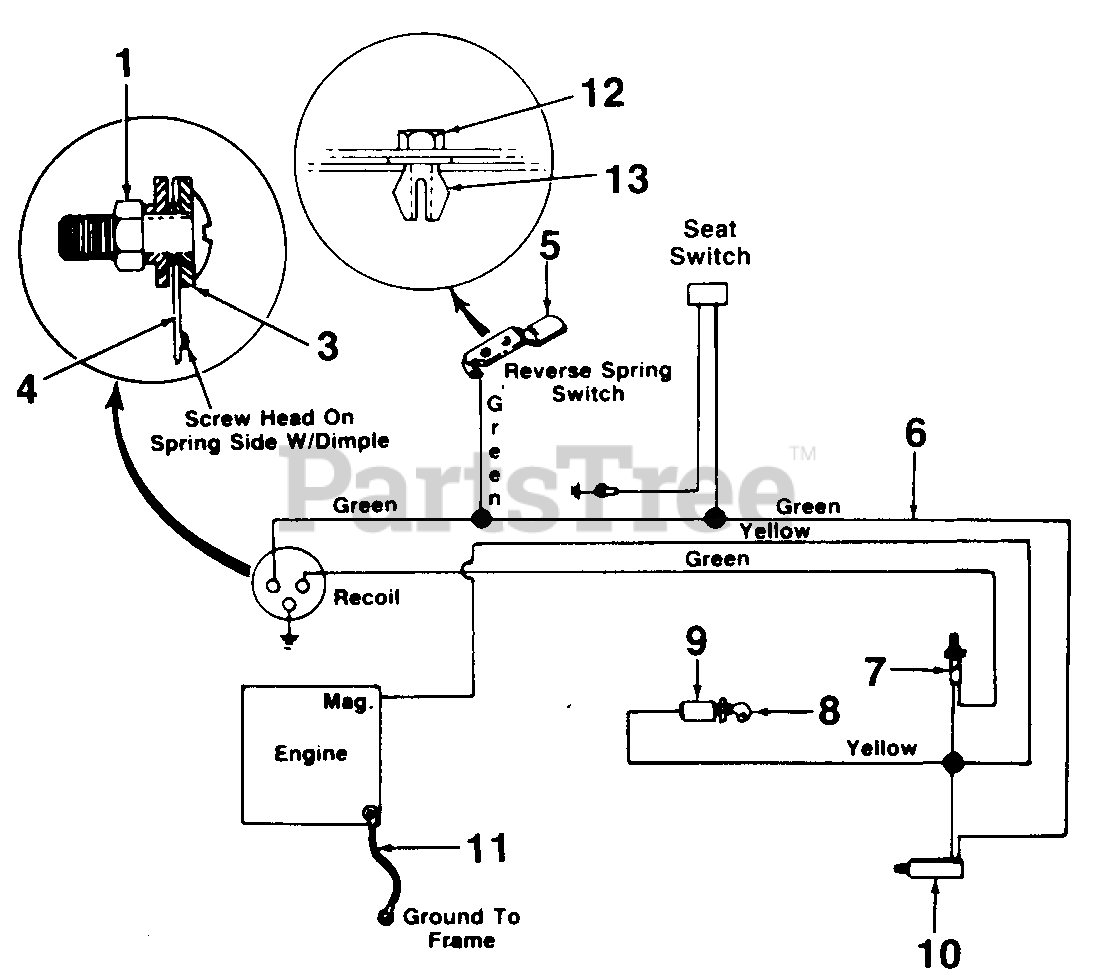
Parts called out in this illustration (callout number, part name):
1	Hex Nut #10-24 Thd.
3	Fiber Washer
4	Switch Spring-Recoil
5	Spring Switch-Reverse
6	Wire Harness
7	Safety Switch-Red N.C.- Clutch
8	Ignition Key
9	Ignition Switch
10	Safety Switch-P.T.O.
11	Ground Wire
12	Truss Mach. Scr. #10-24
13	Push-ln Nut #10
